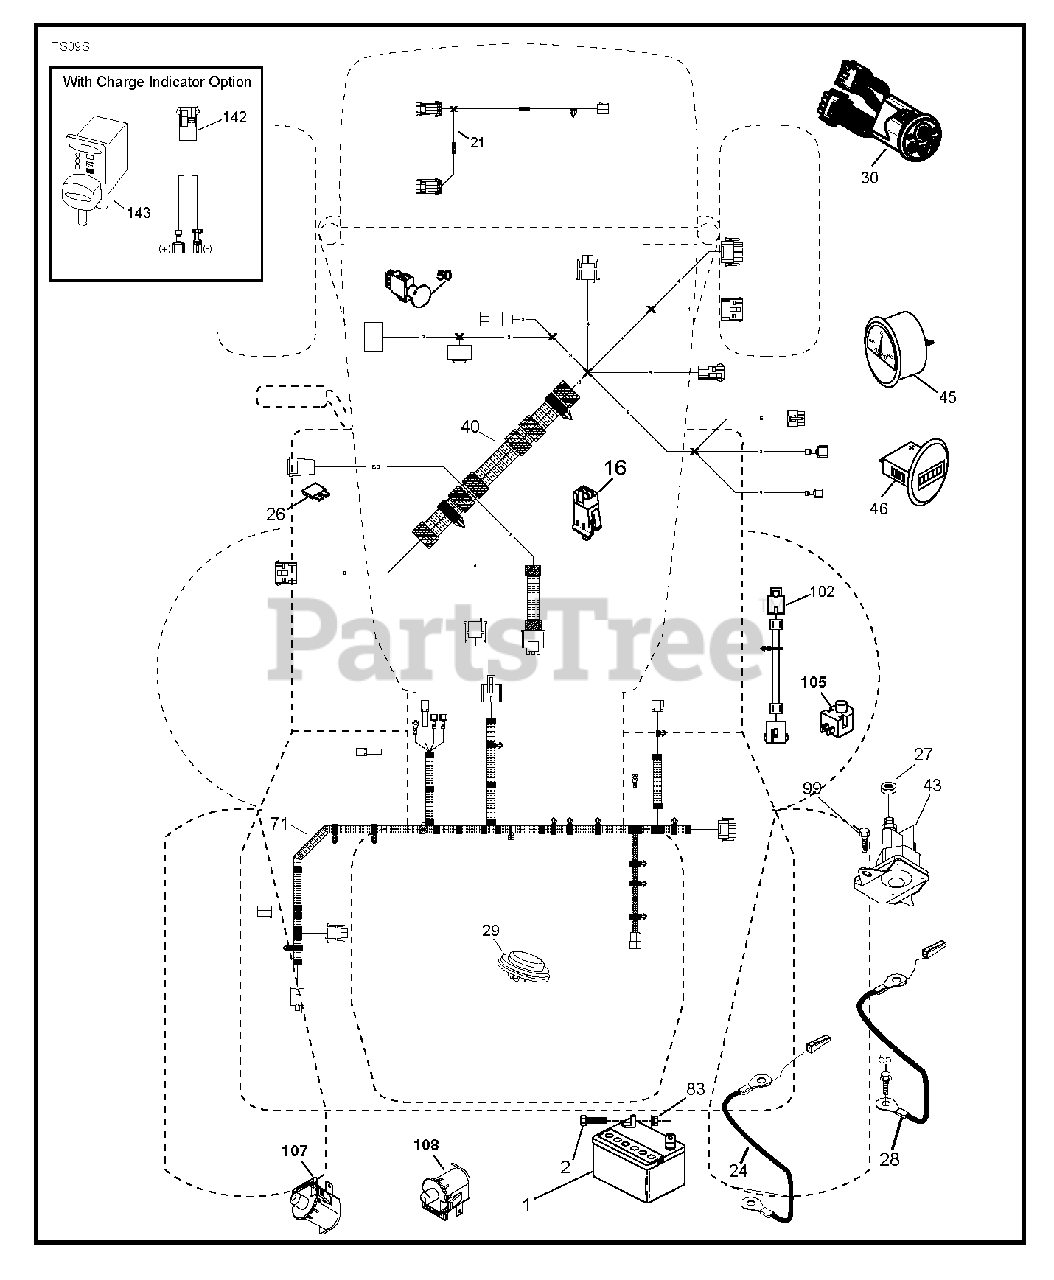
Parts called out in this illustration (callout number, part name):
1	BATTERY BATTERY 14AH 12V LEOC
2	SCREW.HEX.HEAD.CAP.M6 X1.12W
16	SWITCH INTERLOOK PUSH-IN
21	HARNESS LIGHT ASSY TRACTOR,
24	CABLE.BATTERY.POASTIVE.HAM.POS
26	FUSE 20AMP
27	NUT
28	CABLE.GROUND, BATT TO HARN
29	SWITCH.SEAT.OPC.GRY.BUTTON/CAP
30	SMART SWITCH MY14 CRD
40	HARNESS.CHAS.TEX.SIS.FBAT.TWIN
43	SOLENOID.W/BRASS.PLUNGER
45	AMMETER GAUGE ROUND SNAP-IN
46	HOURMETER.GAUGE.RNK.SNAPIN.LS
50	RB PTO.SWITCH.8 TERMINAL.BLACK
55	SCREW 5/16"
71	HARNESS CHAS,TEX,SIS,CRD SMART
83	NUT NUT SQUARE
99	SCREW
102	HARNESS ASSY
105	REVERSE SWITCH
107	.WITCH.FULL BAGGER.INDICATOR
108	PLUNGER SWITCH (COLOR:OLIVE)
142	CHARGE.PORT.PIGTAIL HARNESS
143	CHARGE.PORT
